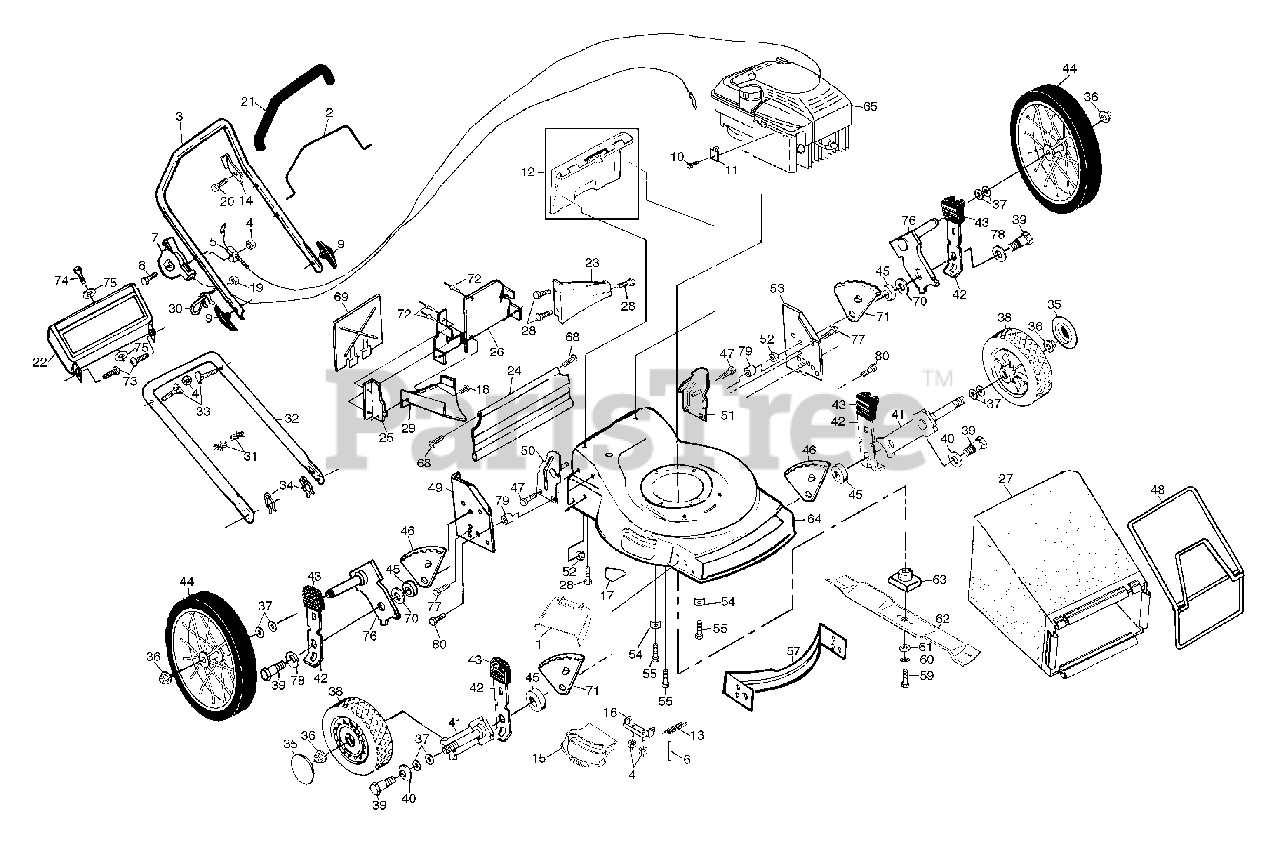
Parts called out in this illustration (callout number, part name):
1	Clip-on Discharge Guard
2	Control Bar
3	Upper Handle
4	Locknut
5	Engine Zone Control Cable
7	Throttle Control
8	Hex Washer Head Screw 1/4-20 x 2-1/8
9	Handle Knob
10	Screw #10 x 5/8
11	Cable Clamp (Engine)
12	Rear Door Kit
13	Hinge Spring
14	Upstop Bracket
15	Combi-cut Door
16	Hinge Bracket
17	Danger Decal
19	Keps Locknut 1/4-20
20	Hex Washer Head Screw #10-24
21	Handle Grip
22	Trim Plate
23	Rear Baffle
24	Rear Skirt
25	Side Baffle
26	Back Plate
27	Grass Bag
28	Screw Hex Head 1/4-20 x 1/2
29	Discharge Baffle
30	Rope Guide
31	Cable Clips
32	Lower Handle
33	Handle Bolt
34	Hairpin Cotter
36	Flanged Locknut
37	Wave Washer
38	Wheel & Tire Assembly (Front)
39	Shoulder Bolt
40	Belleville Washer
41	Axle Arm
42	Selector Spring
43	Selector Knob
44	Wheel & Tire Assembly (Rear)
45	Spacer
46	Wheel Adjusting Bracket R.R.
47	Self-tapping Screw 5/16-18 x 3/4
48	Catcher Frame
49	Wheel Support Bracket (Right)
50	Handle Bracket (Right)
51	Handle Bracket (Left)
52	Locknut 3/8-16
53	Wheel Support Bracket (Left)
54	Engine Washer
55	Hex Head Thread Rolling Screw 3/8-16 x 1
57	Front Baffle
59	Hex Head Machine Screw 3/8-24 x 1-3/8 Gr. 8
60	Helical Lock Washer
61	Hardened Washer
63	Blade Adapter
64	Lawn Mower Housing Kit
68	Hinge Screw
69	Mulcher Plate
70	Flat Washer
71	Wheel Adjusting Bracket L.R.
73	Screw #10-24 x .625
74	Screw 1/4-20 x 1.50
75	Flat Washer 28 x .62 x .02
76	Axle Arm Assembly
78	Washer
